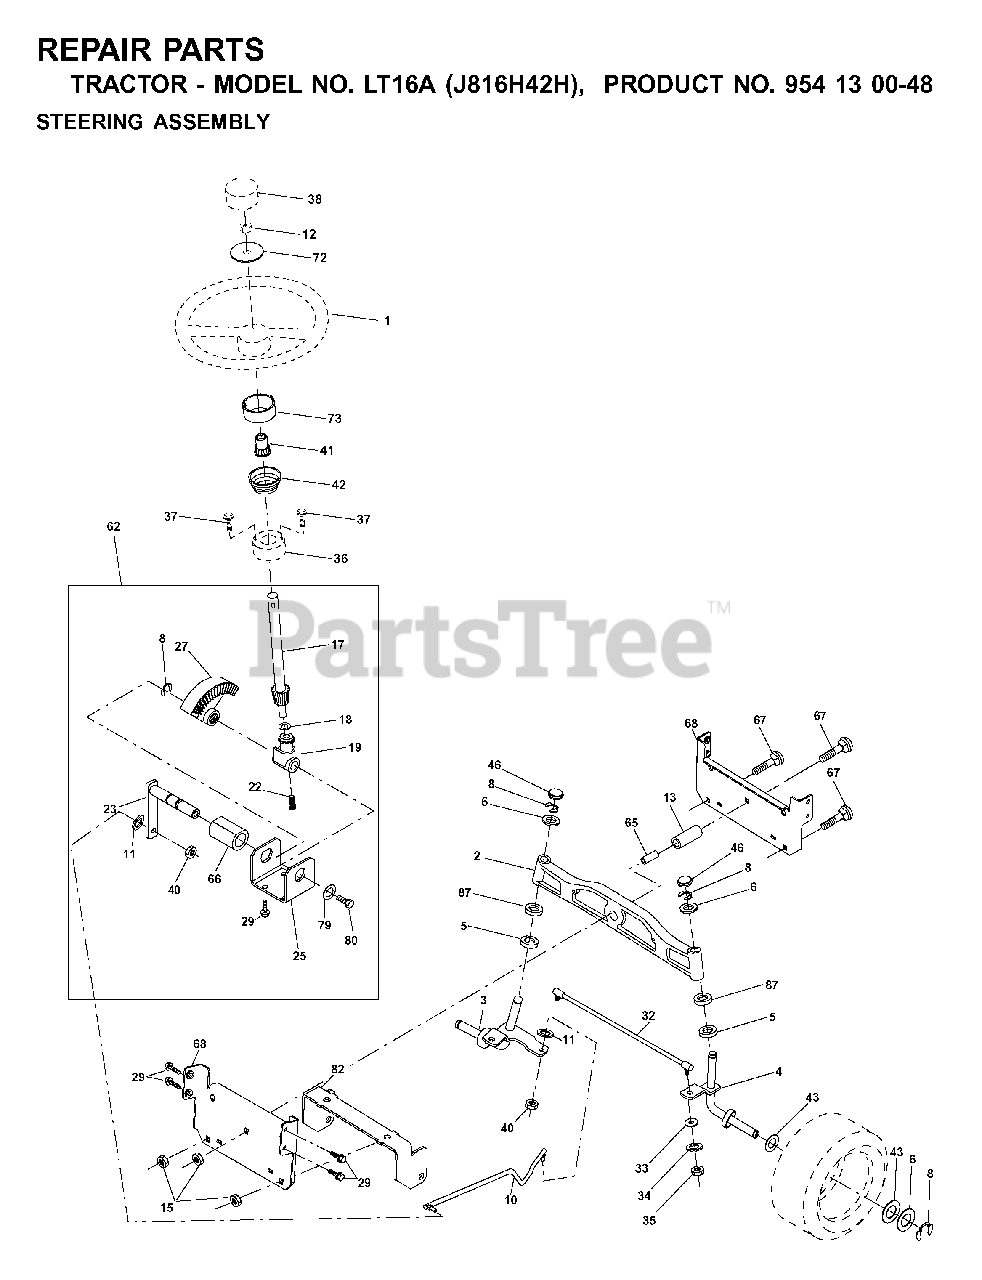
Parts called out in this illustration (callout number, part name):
2	AXLE ASM
3	SPINDLE.ASM.LH.15"TIRES
4	SPINDLE.ASM.RH.15"TIRES
8	RING CLIP
10	DRAGLINK.15".TIRES
11	WASHER, LOCK 3/8
12	NUT.HEX.1/2-20
13	TUBE, PIVOT AXLE
15	NUT
17	STEERING SHAFT
18	THRUST WASHER
19	STEERING SHAFT SUPPORT
22	SCREW.HX.WSH.HD
23	SHAFT ASSY PITTMAN
25	BRACKET STEERING
27	GEAR.SECTOR
29	SCREW 3/8-16X3/4
33	WASHER M
34	LOCKWASHER
35	NUT, CROWNLOCK
36	BUSHING, STRG. BLK
40	GRIPCO NUT
41	STEERING WHEEL ADAPTOR
46	CAP.SPINDLE
65	SPACER BRACE AXLE
66	BEARING ARM
67	BOLT
68	BRACE.AXLE.15"TIRES
80	BOLT.HX.NYLON3/8-16X
82	BRACKET
87	WASHER, FLAT .781 X 1 1/2"
